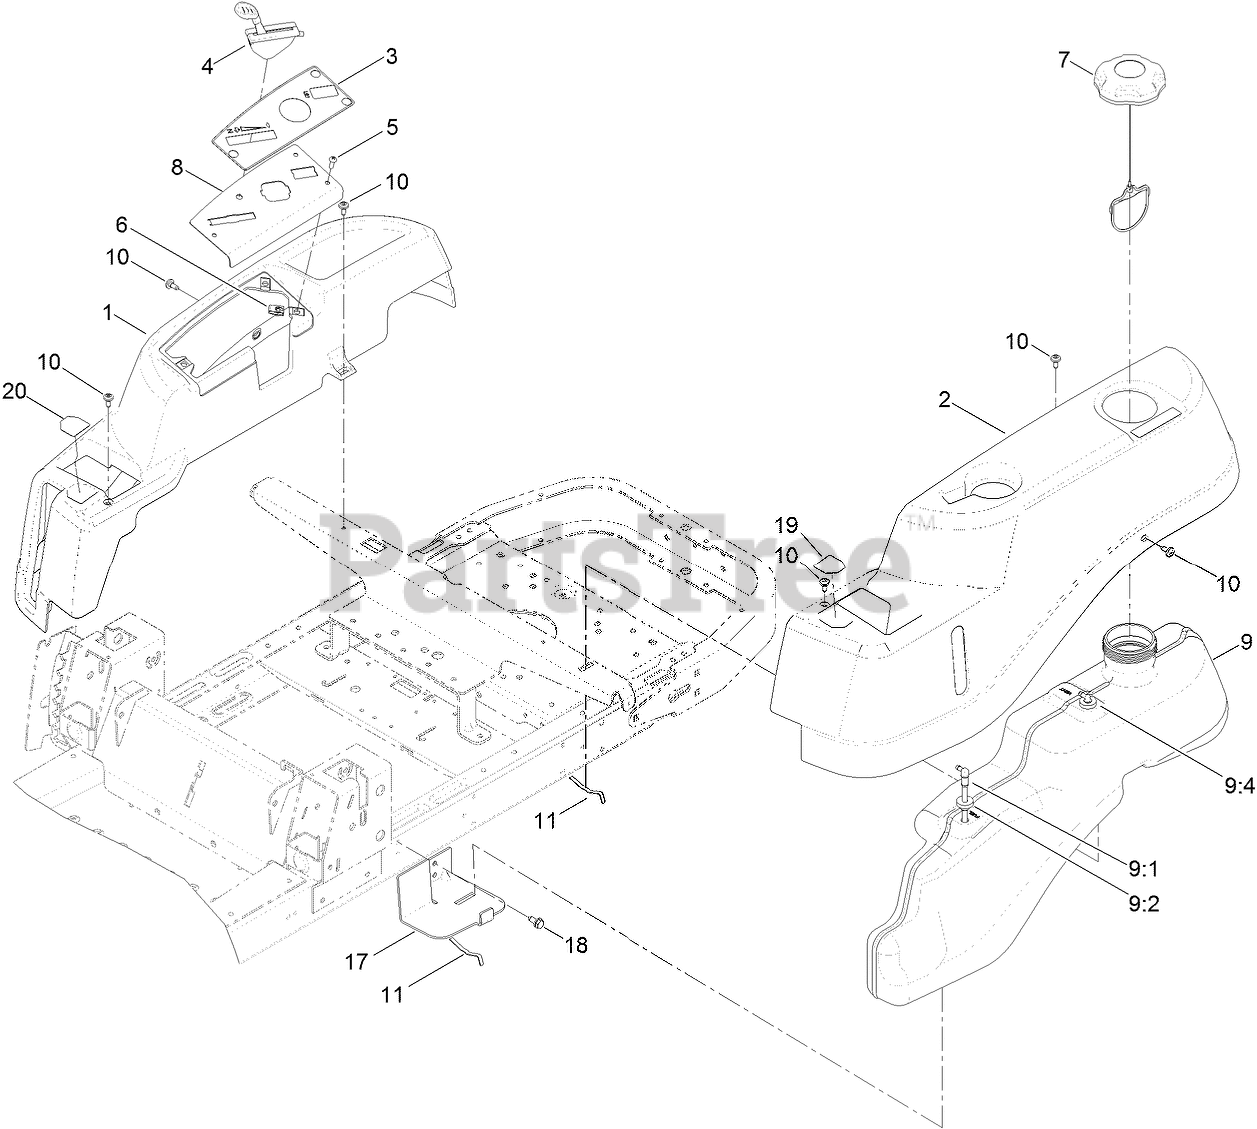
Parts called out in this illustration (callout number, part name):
1	POD-RH
2	POD-LH
3	DECAL-PANEL, CONTROL
4	CABLE-THROTTLE AND CHOKE
5	SCREW-PRH
7	CAP-FUEL, RATCHETING
8	PLATE-CONTROL
9	FUEL TANK ASM
9:1	CONNECTOR-ELBOW, 90 DEG
9:2	BUSHING
9:4	FITTING-PLASTIC
10	SCREW-SHOULDER
11	SPRING
17	SUPPORT-TANK, FRONT
18	SCREW-HWHTF
19	DECAL-CONTROL LEVER, LH
20	DECAL-CONTROL LEVER, RH
